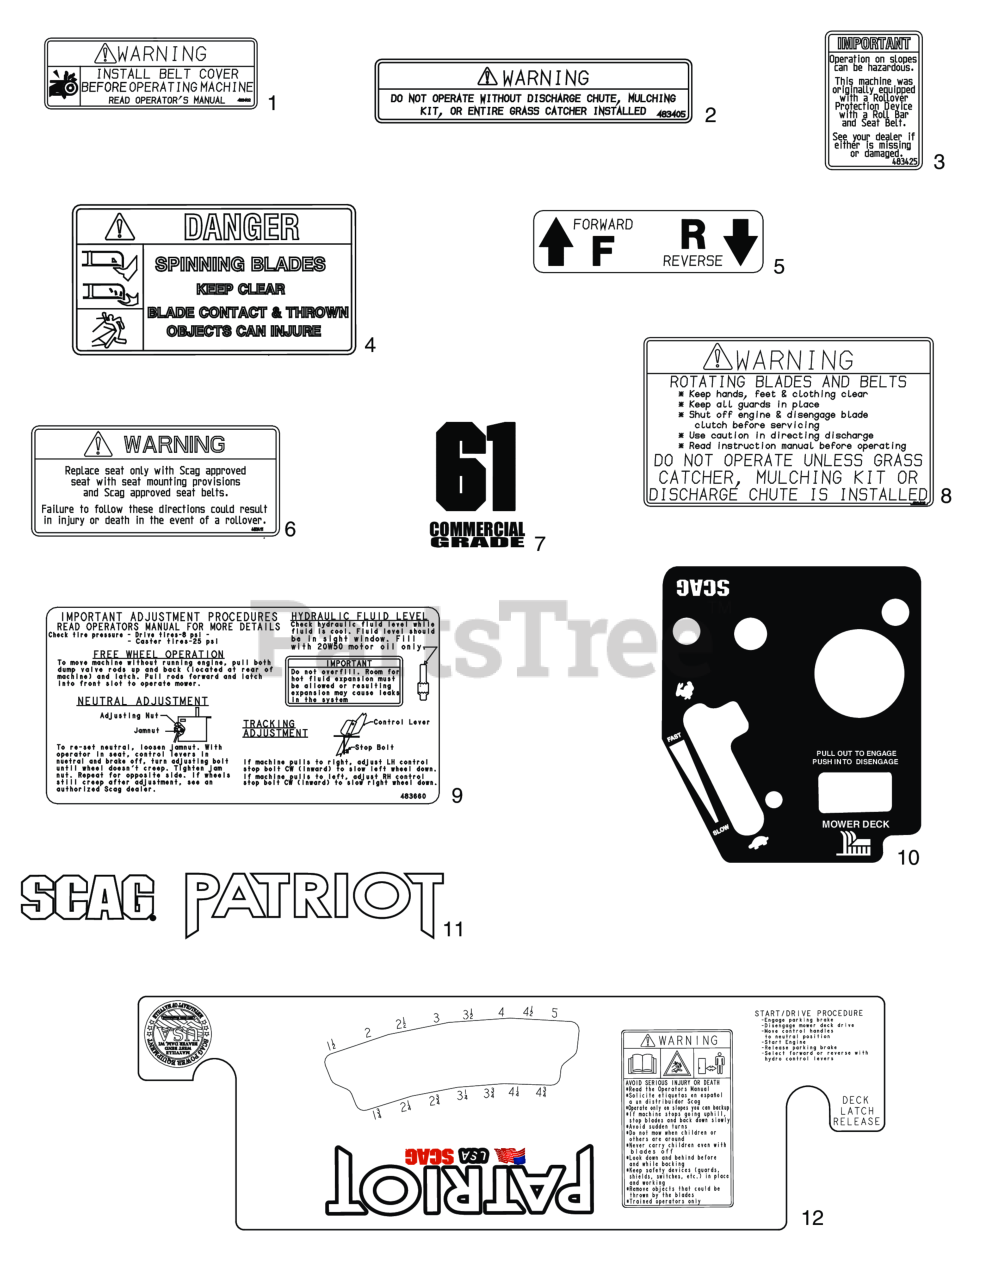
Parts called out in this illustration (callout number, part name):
1	Decal, Warning - Belt Cover
2	Decal, Warning-Discharge
3	Decal, ROPS
4	Decal, Spinning Blades
5	Decal, Traction Control
6	Decal, Seat Replacement
7	Decal, 52 Commercial
8	Decal, Warning - Rotating Blades
9	Decal, Adjustment SFZ
10	Decal, Instrument Panel
11	Decal, Front SPZ, (Scag Gold Logo)
12	Decal, Cutting Height, (Scag Gold Logo)
